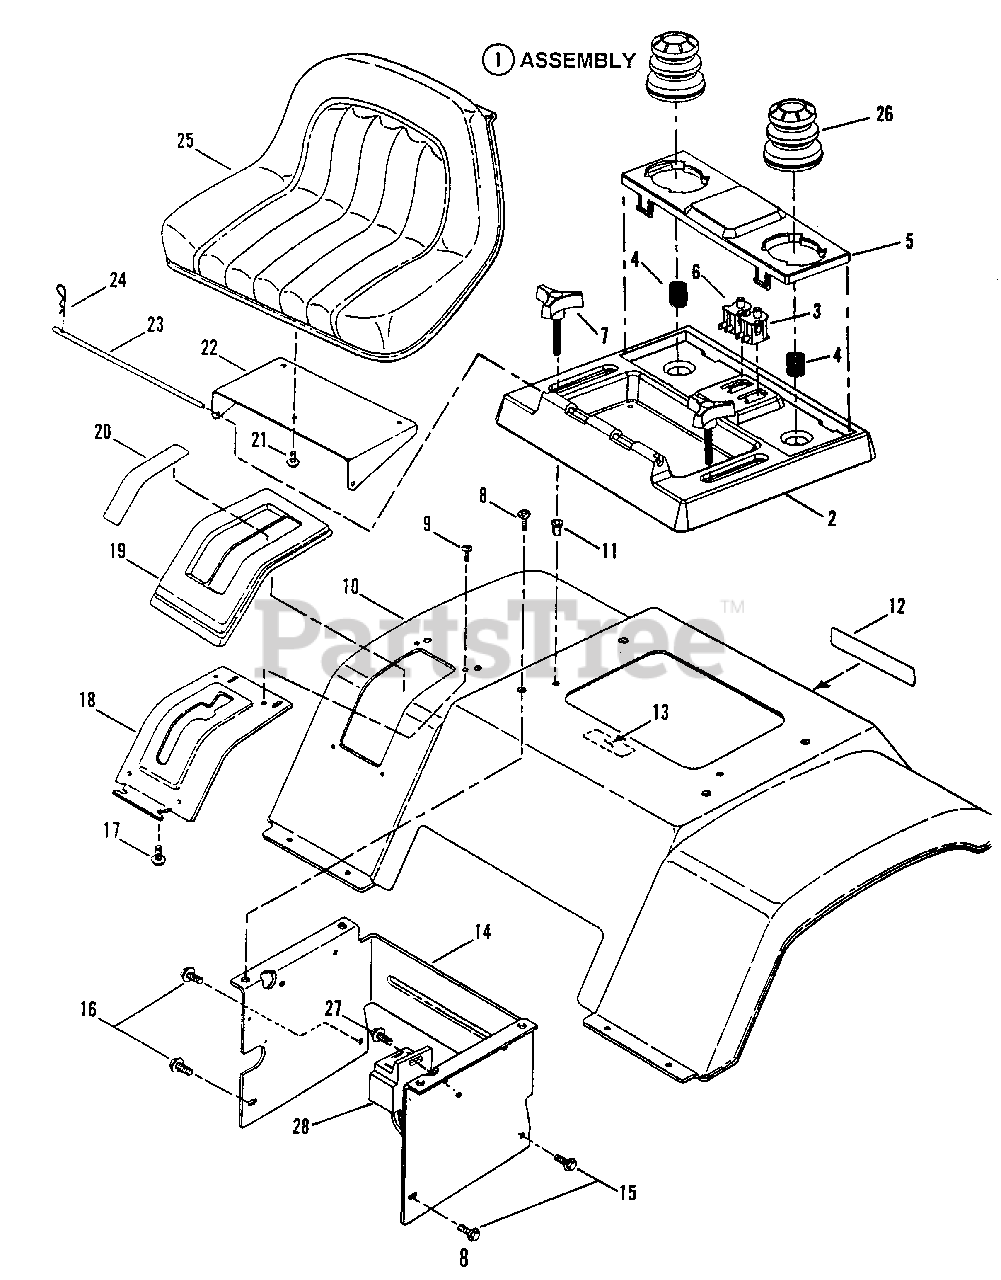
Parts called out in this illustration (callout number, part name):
1	ASSEMBLY, Seat Support
2	SUPPORT, Seat
3	SWITCH, Seat, Gray, NC
4	SPRING
5	HOLDER, Cushion
6	SWITCH, Seat
7	KNOB, Seat Adjustment, 5/16-18 x 2
8	SCREW, 5/16-18 x 5/8" Truss Head, Torx
9	SCREW, 1/4-20 x 5/8 Hex Washer Head, Self-Tapping
10	PAN, Seat (Fender)
11	RIV-NUT, 5/16-18 Round
12	DECAL - SNAPPER, 7.28 Molded Logo, Silver Letters & Blue Stripe
13	DECAL - CAUTION, Battery Location
14	SUPPORT, Fender
15	SCREW, 5/16-18 x 5/8" Hex Washer Head, Swage Form
16	SCREW, 5/16-18 x 1-1/4 Hex Washer Head, Swage Form
17	SCREW, #10-16 x 1/2" Hex Washer head, Self-Tapping
18	DETENT, Shift
19	COVER, Shift
20	DECAL, Shift Cover, 5-Speed
21	BOLT, 5/16-18 x 1/2' Hex Flange Lock, Grade 5
22	BRACKET, Seat Support
23	ROD, Seat Hinge
24	PIN, 3/32 x 1-1/2 Hair
25	SEAT
25	SEAT, V1400
26	CUSHION, Seat
27	SCREW, #10-24 x 1/2" Hex Washer Self-Tap (Torx)
28	RECEPTACLE, Female Wire Harness Relay
